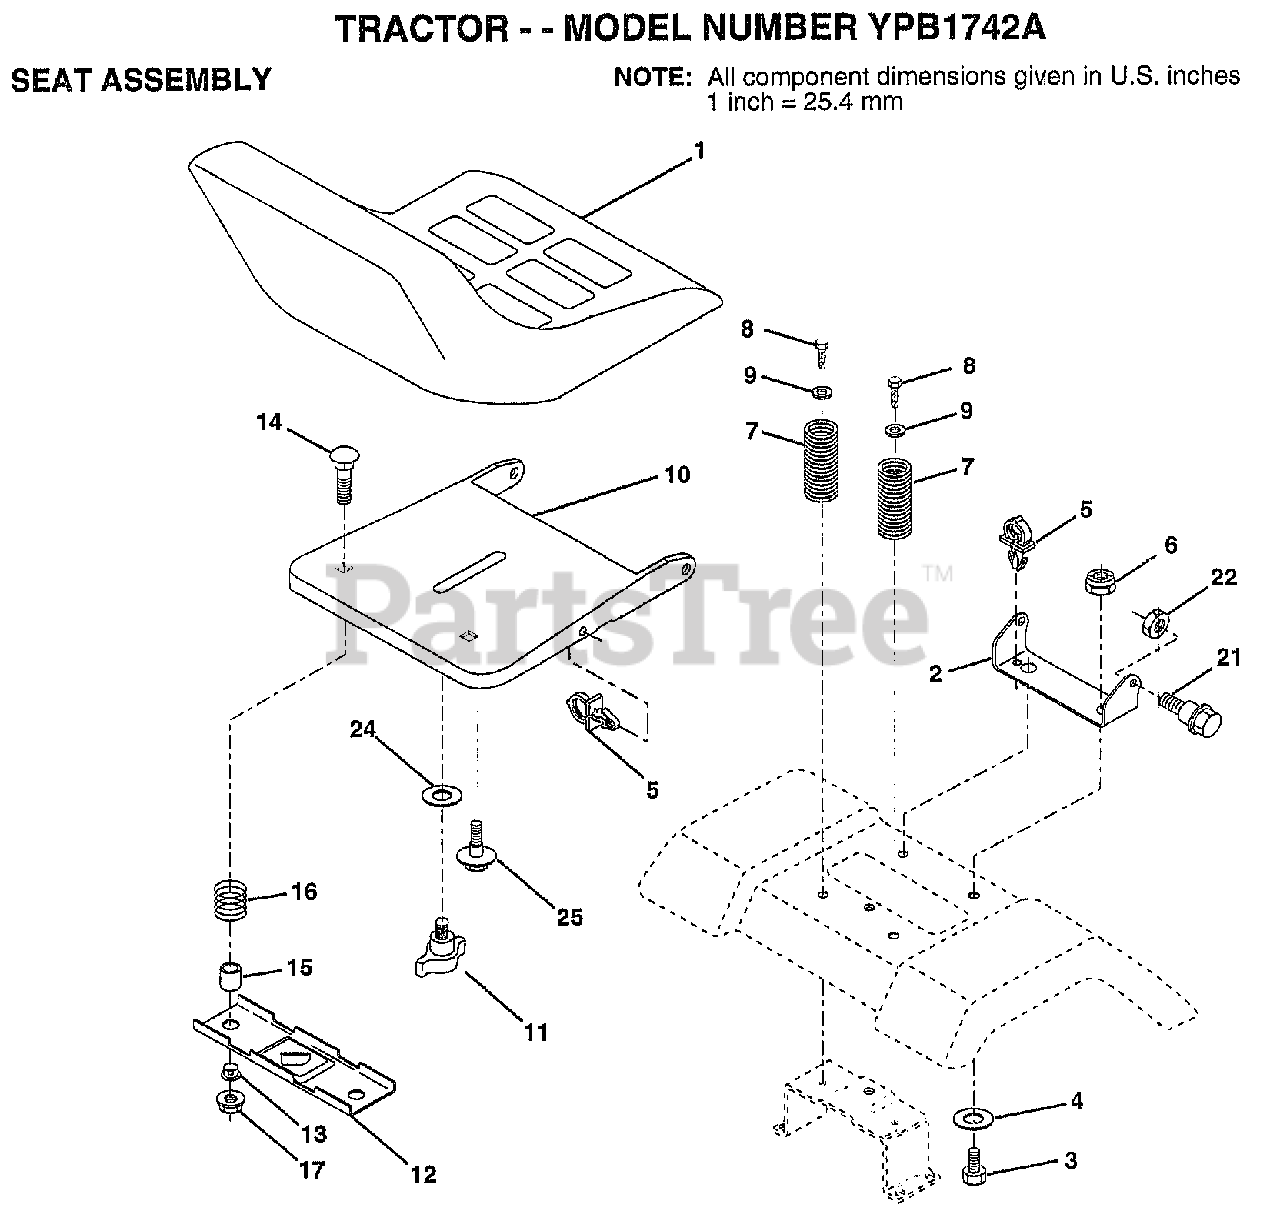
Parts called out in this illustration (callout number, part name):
1	SEAT.2400/1416.BK
2	BRACKET PVT SEAT
3	BOLT
4	WASHER PM
5	CLIP.PUSH-IN.HING
6	NUT
7	SPRING COMPRESSIO
8	SCREW GTV
9	WASHER
10	PAN-SEAT
11	KNOB.SEAT.ADJ.WINGNUT
12	BRKT SWITCH
13	BUSHING
14	BOLT-RD HD SQ NK
15	SPLIT SPACER
16	SPRING
21	"BOLT,SHOULDER"
22	NUT
24	WASHER
25	"BOLT,SHOULDER"
